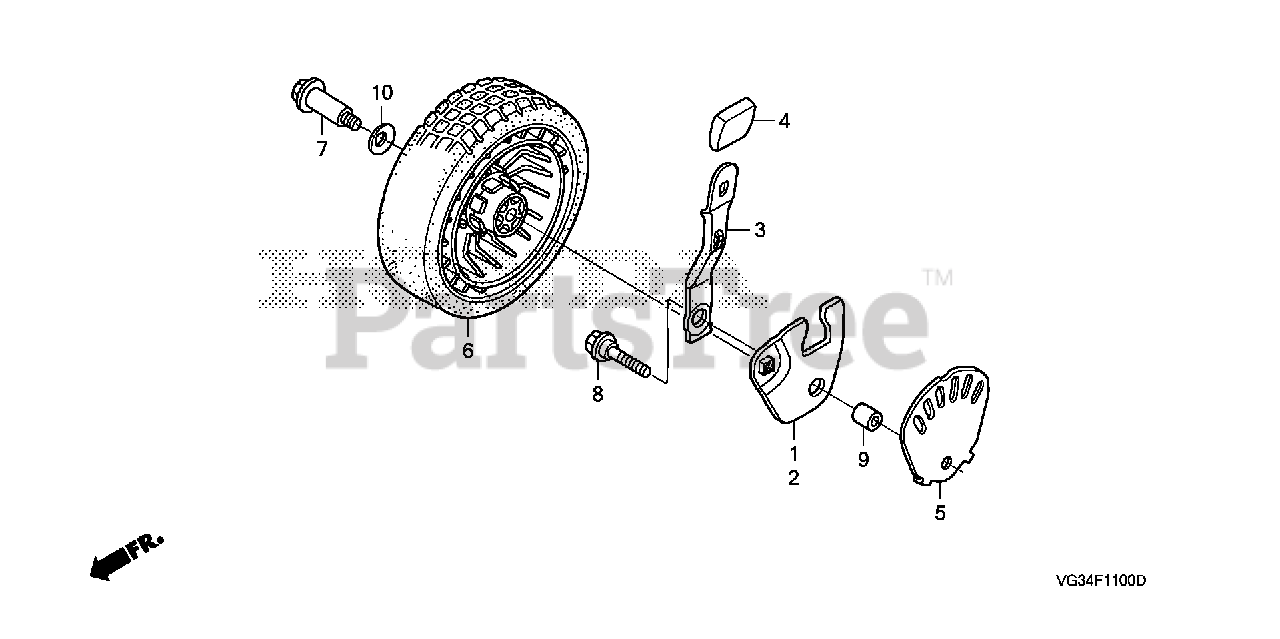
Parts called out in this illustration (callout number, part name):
1	ARM, R. FR. ADJUSTING
2	ARM, L. FR. ADJUSTING
3	PLATE, FR. ADJUSTER
4	GRIP, ADJUSTER
4	GRIP, ADJUSTER *NH105* (MAT BLACK)
5	PANEL, FR. ADJUSTER
6	WHEEL, FR.
7	BOLT, FR. WHEEL SHAFT
8	BOLT, ADJUSTER ARM
9	COLLAR, FR. ADJUSTING
10	WASHER, WHEEL
